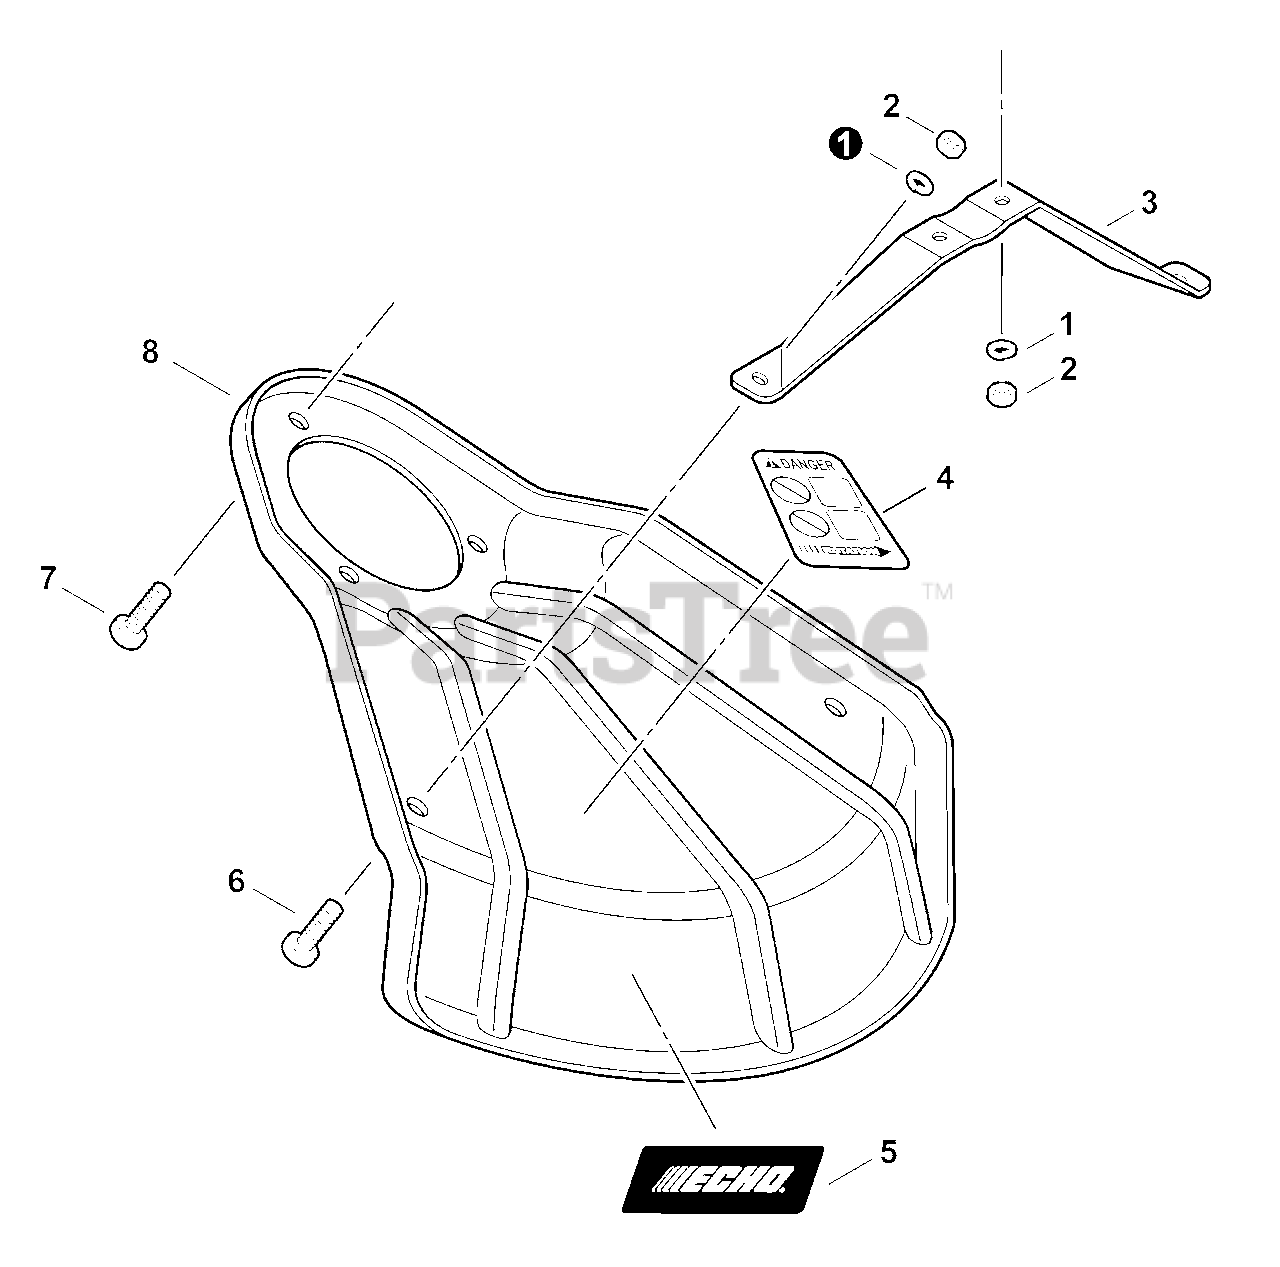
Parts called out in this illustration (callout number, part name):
1	WASHER, SPRING 5
2	NUT M5
3	BRACKET, SHIELD MOUNTING
4	LABEL, DANGER
5	LABEL, ECHO
6	BOLT, TORX 5×8
7	BOLT, TORX 5×10
8	SHIELD, METAL DEBRIS
